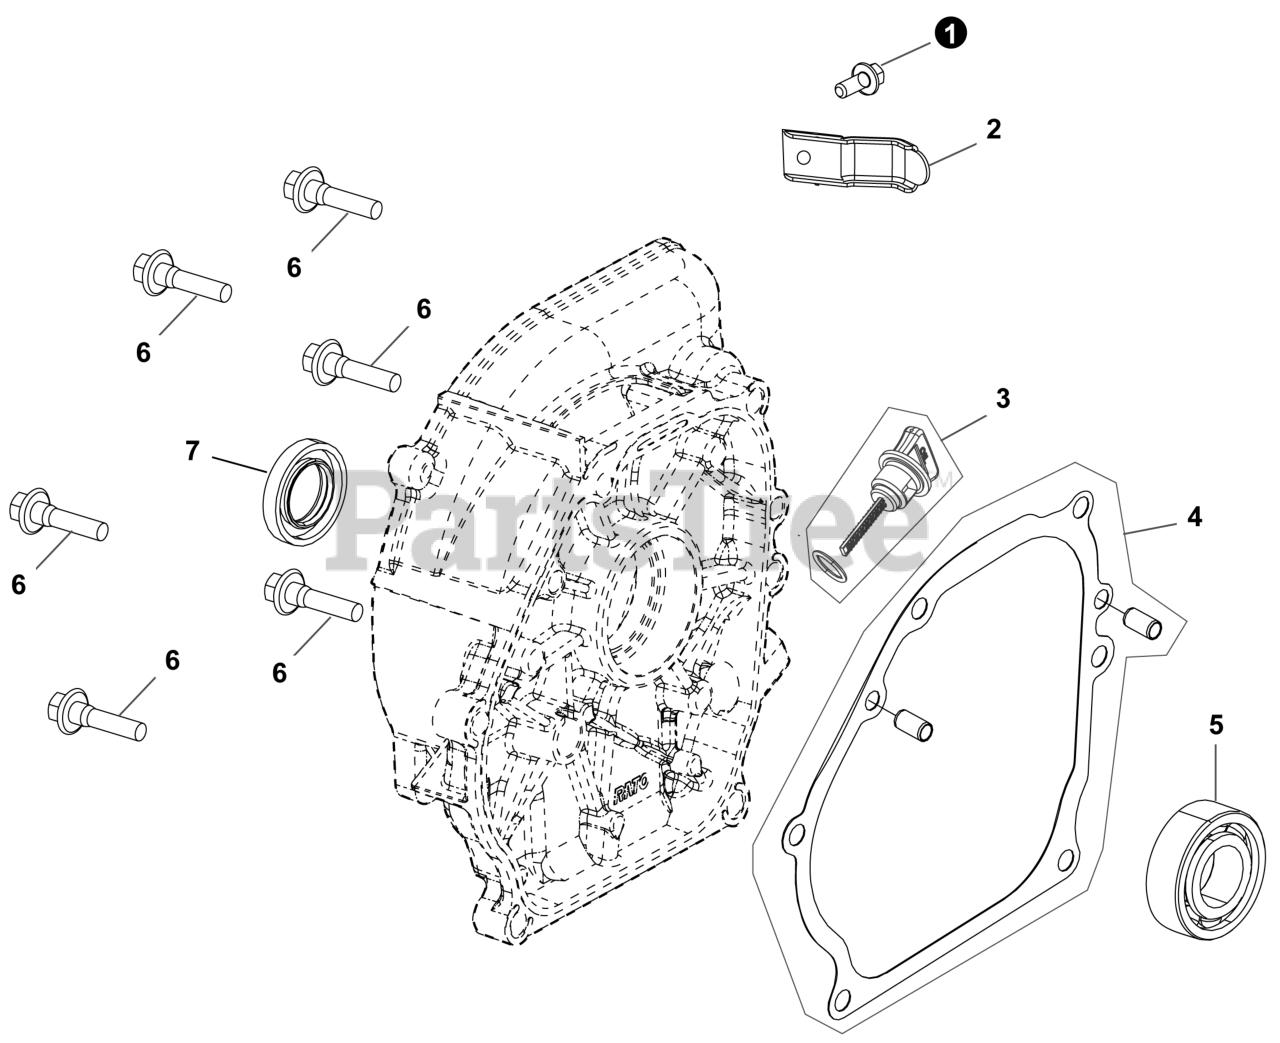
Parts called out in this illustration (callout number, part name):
3	DIPSTICK SUBASSEMBLY, OIL
4	GASKET, CRANKCASE
5	BEARING, CRANKSHAFT
7	SEAL, OIL
